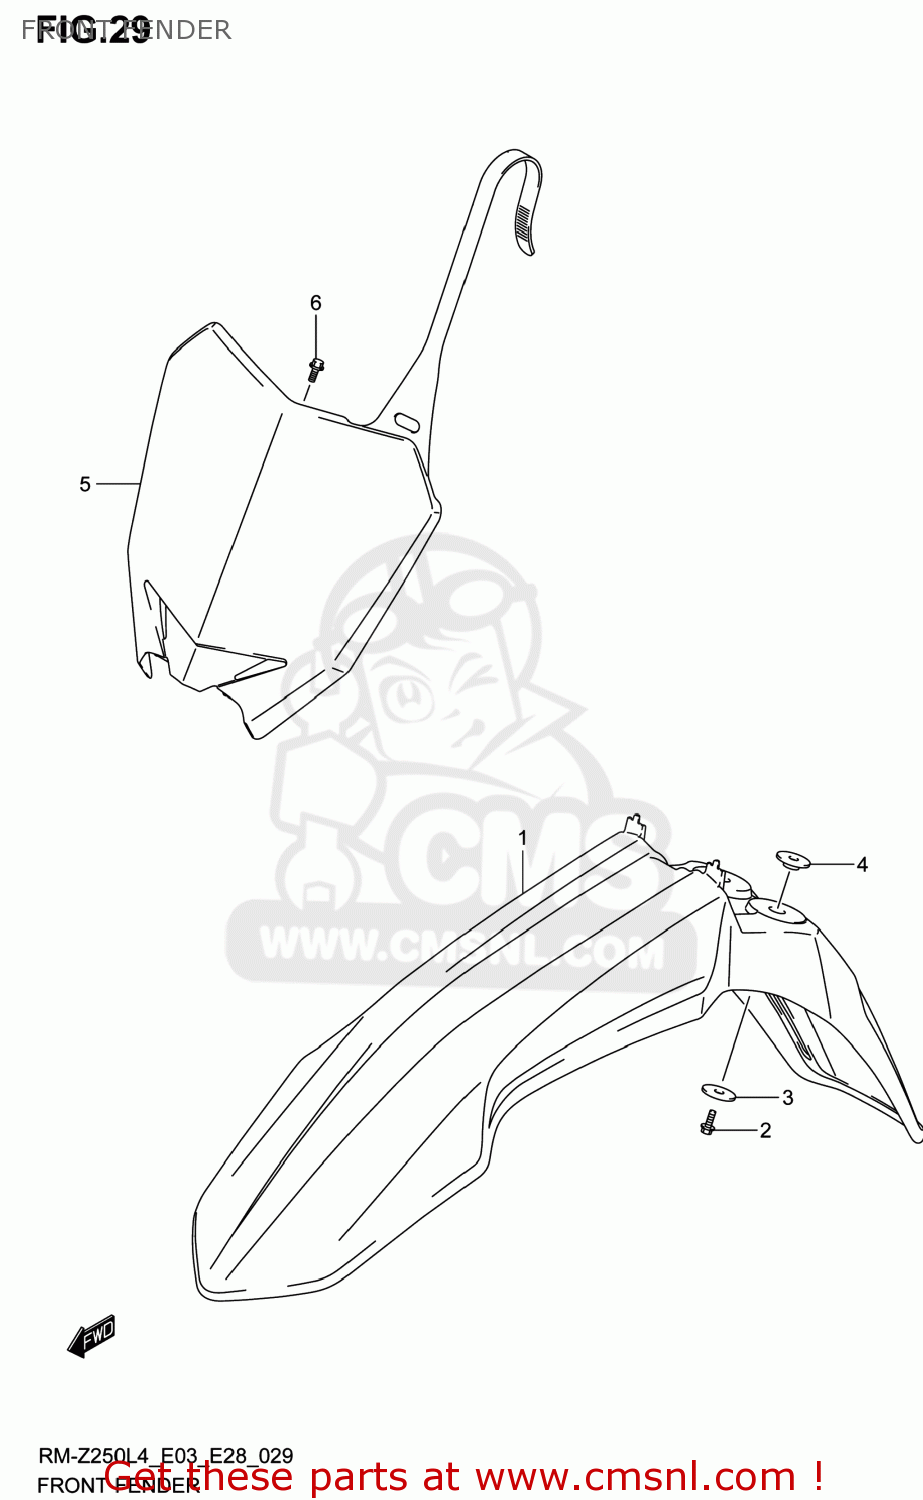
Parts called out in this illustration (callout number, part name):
1	FENDER,FR
2	BOLT
3	WASHER,FUEL TANK FR
4	WASHER
5	PLATE,NUMBER FR
6	BOLT(6X12)
